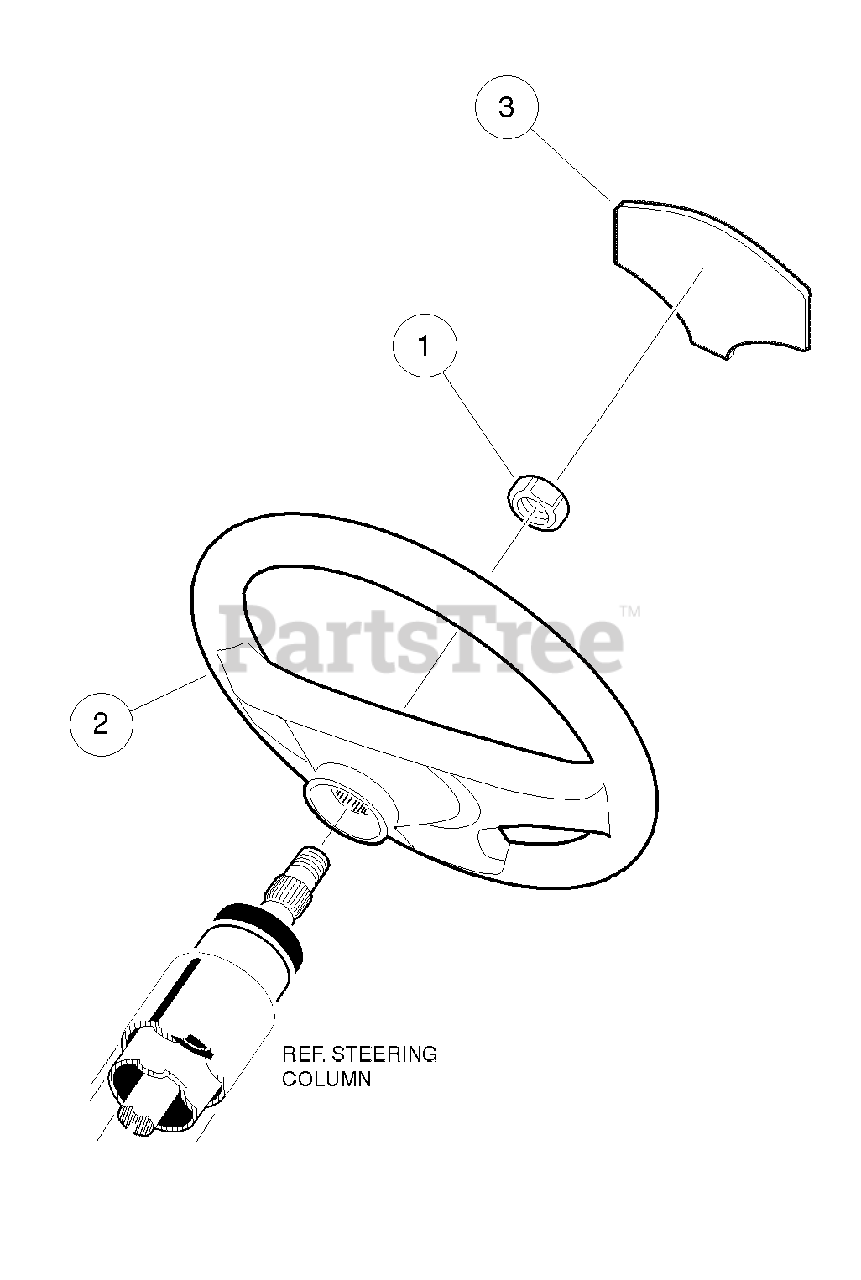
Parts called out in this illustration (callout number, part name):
1	Nut, 5/8-18 Nylon Insert Jam
2	Steering Wheel, Spline
3	Wheel Center
